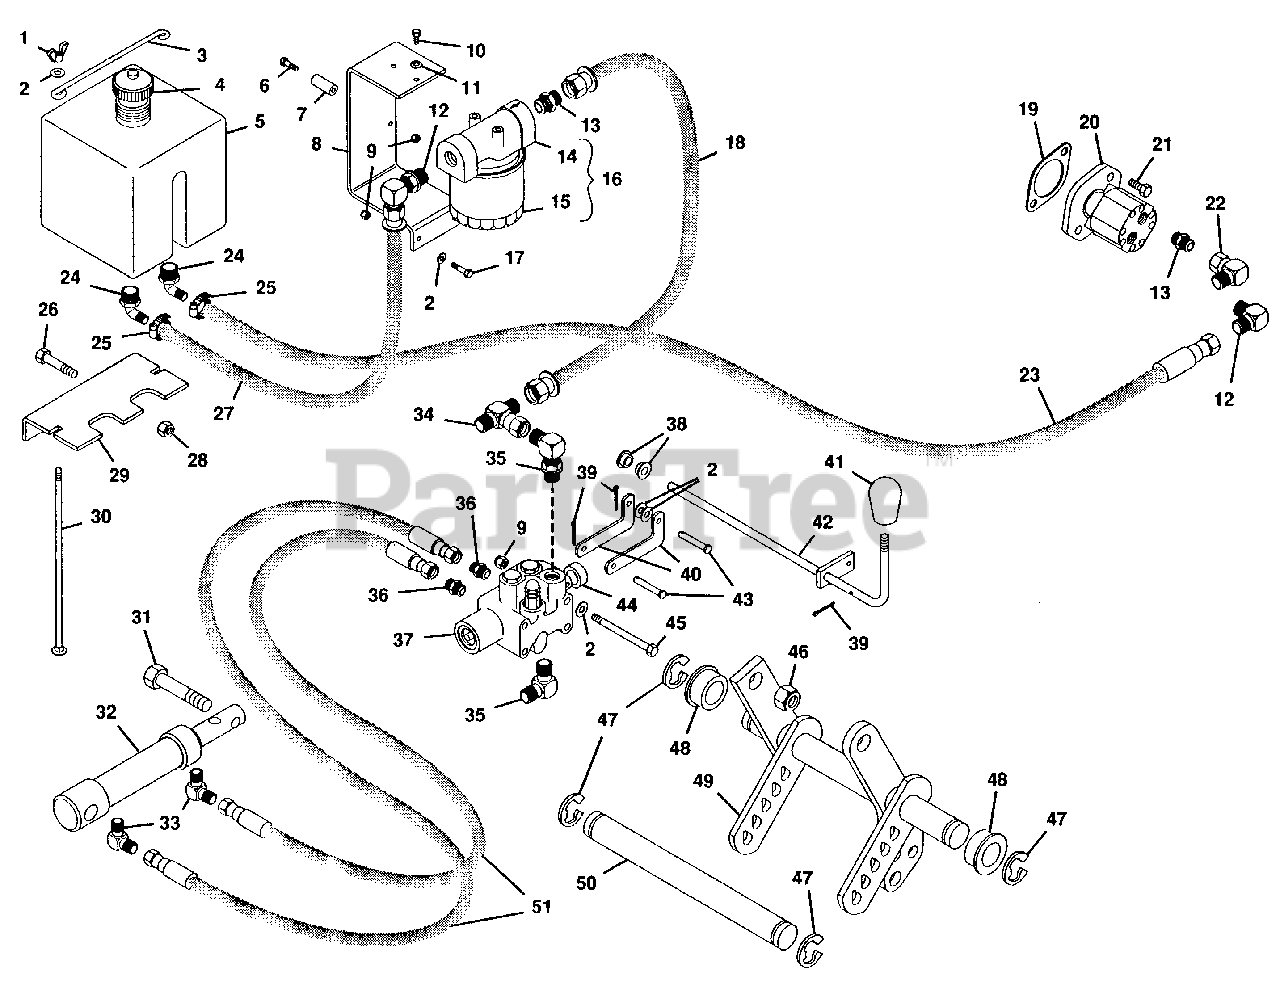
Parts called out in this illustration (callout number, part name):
1	NUT, WING 1/4-20
2	WASHER, FLAT .281X.625X.065
3	ROD, OIL TANK HOLD-DOWN
4	CAP, TANK
5	TANK, HYDRAULIC
6	BOLT, HEX 1/4-20X1.75
7	BUSHING, TANK SUPPORT
8	BRACKET, OIL FILTER MOUNTING
9	NUT, LOCK 1/4-20
10	BOLT, HEX 1/4-20X.625
11	WASHER, LOCK 1/4 REG.
12	ADAPTOR, P-H #2503-8-8
13	ADAPTOR, 0503-8-6
14	BASE, FILTER
15	ELEMENT
16	FILTER, SPIN-ON LUBE
17	BOLT, HEX 1/4-20X.75
18	HOSE, HYDRAULIC VALVE TO FILTER
19	GASKET, COVER PLATE
20	PUMP, HYDRAULIC 24-G
21	BOLT, HEX 3/8-16X.75
22	ADAPTOR(P-H #3903-6-6)
23	HOSE, TANK TO PUMP
24	FITTING MALE ELBOW 1/2X1/2
25	CLAMP, .88 DIA. HOSE
26	BOLT, HEX 5/16-18X.75
27	HOSE, OIL FILTER TO TANK
28	NUT, LOCK 5/16-18
29	SUPPORT, HYDRAULIC OIL TANK
30	BOLT, 1/4-20X8.00 RD HD SQ NK
31	BOLT, HEX 1/2-13X2.00
32	CYLINDER, HYDRAULIC
33	ADAPTOR(P-H #2503-4-4)
34	ADAPTER, T. FLEX
35	ADAPTOR(P-H #2503-6-6)
36	ADAPTOR(P-H #0503-4-4)
37	VALVE, HYDRAULIC
38	BUSH., FLG. .520X.750X.375 NY.
39	PIN, COTTER .094X.75
40	ROD, HYDRAULIC CONTROL
41	KNOB, PTO
42	WELDMENT, HYDRAULIC VALVE ROD
43	PIN, CLEVIS
44	BUSH., ST. .700X1.00X.300 STL.
45	BOLT, HEX 1/4-20X2.75
46	NUT, LOCK 1/2-13
47	E-RING, 1.000 SHAFT
48	BUSH., FLG. 1.03X1.75X.750 NY.
49	WELDMENT, LIFT LEVER SHAFT
50	SHAFT, HYDRAULIC CYLINDER
51	HOSE, HYDRAULIC 14.5
NS	SEALANT, PLASTIC THREAD
